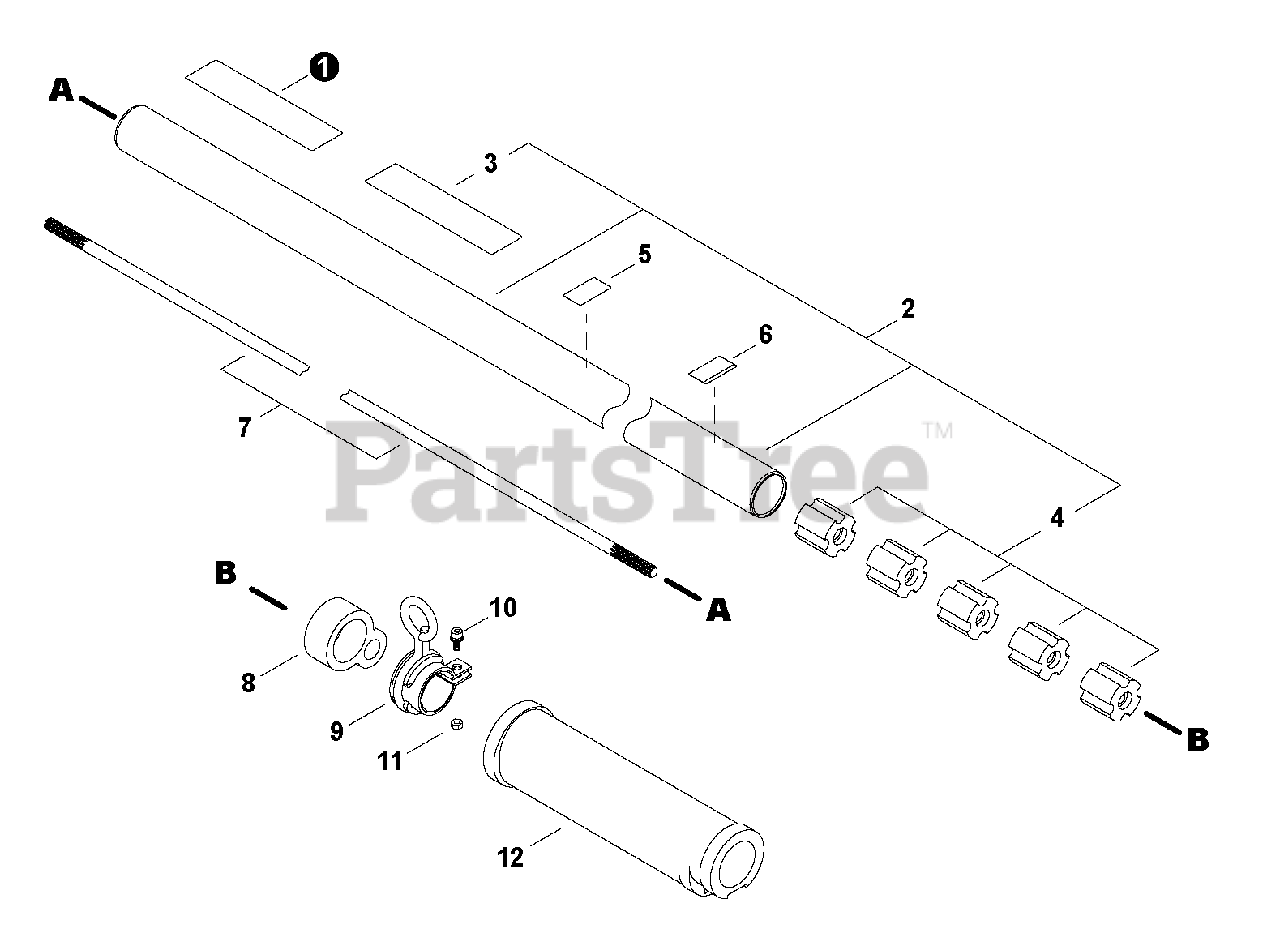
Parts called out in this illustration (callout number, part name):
1	Label, Shindaiwa Professional
2	Pipe Assy, Main
3	Label, Caution (Blade Capable)
4	Bushing
5	Label, Handle
6	Label - Alignment
7	Mainshaft
8	Holder, Cable
9	Hanger, Swivel
10	Bolt 5
